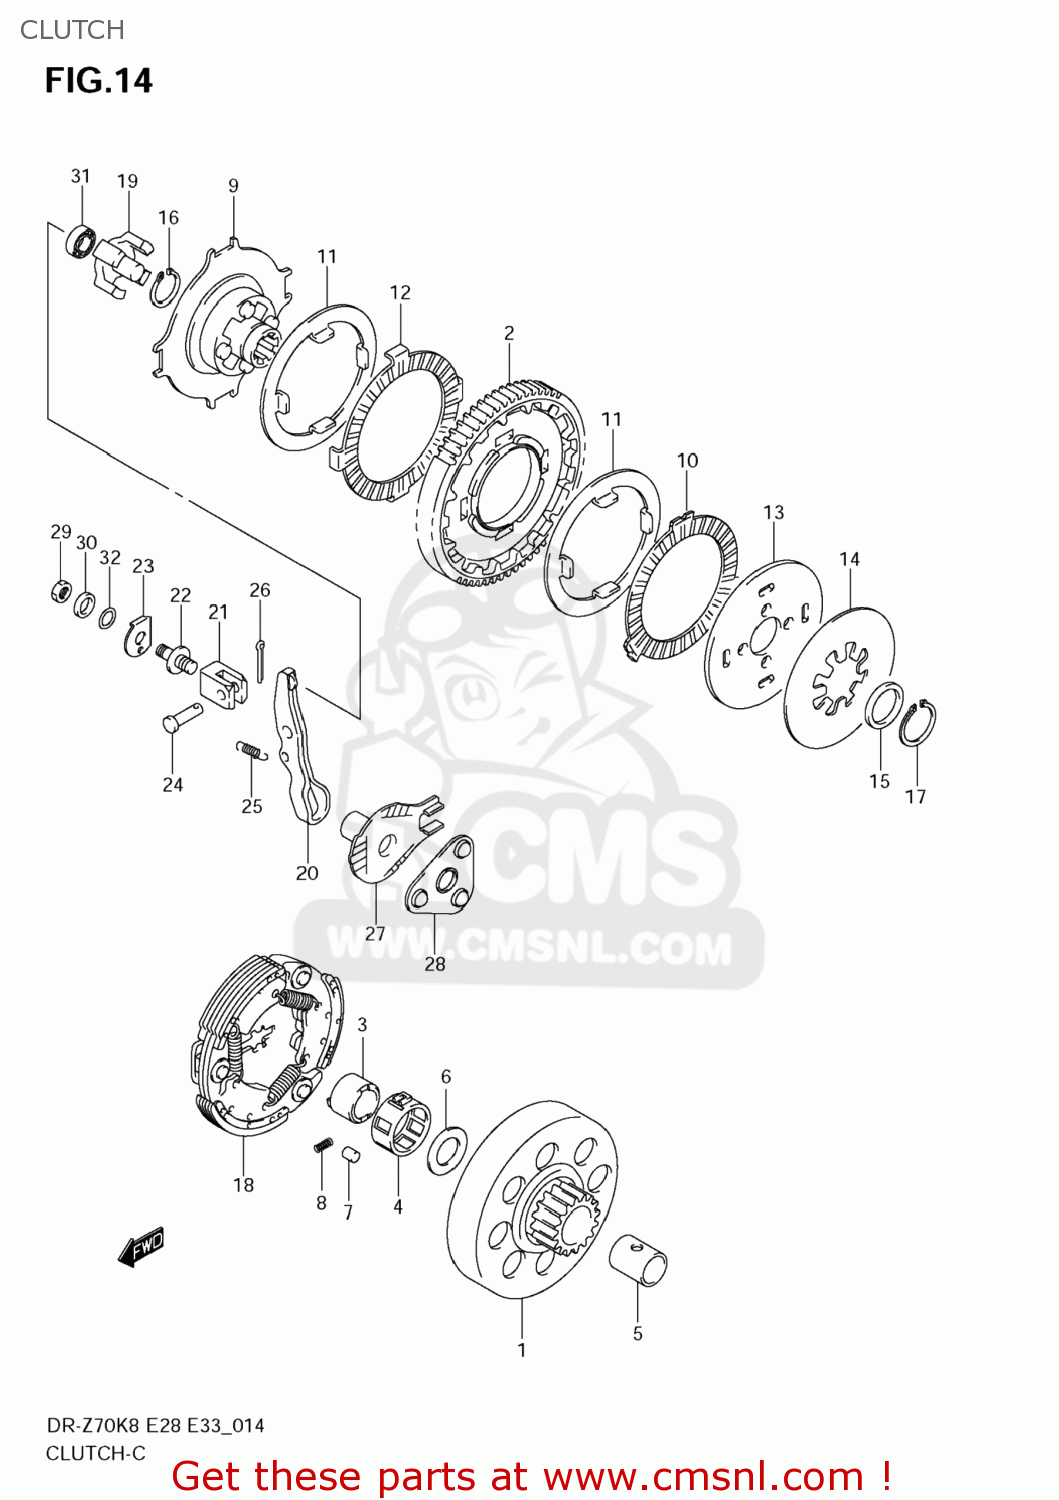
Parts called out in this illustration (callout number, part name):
1	GEAR,PRIMARY DRIVE(NT:65)
2	TANDWIEL. PR.
3	RACE,ONE WAY CLUTCH
4	RETAINER,ONE WAY CLUTCH
5	SPACER(16X21X23.5)
6	SHIM(16X28X0.5)
7	ROLLER(7X10)
8	SPRING
9	HUB,CLUTCH SLEEVE
10	PLATE,CLUTCH DRIVE (NAS)
11	PLATE,CLUTCH DRIVEN (NAS)
12	PLATE,CLUTCH DRIVEN NO.2 (NAS)
13	PLATE,CLUTCH PRESSURE
14	WASHER
15	SPACER(22X28X4)
16	CIRCLIP
17	CIRCLIP
18	CLUTCH ASSY,SHOE (NAS)
19	PIECE,CLUTCH PUSH
20	ARM,CLUTCH RELEASE
21	BOSS,CLUTCH RELEASE ARM
22	BOLT,CLUTCH RELEASE ADJUST
23	WASHER
24	PIN
25	SPRING
26	PIN
27	GUIDE,RELEASE BALL OUTER
28	BALL,CLUTCH RELEASE
29	NUT
30	WASHER(6.5X13X3.2)
31	BEARING(16X6)
32	O RING(D:1.9,ID:5.7)
